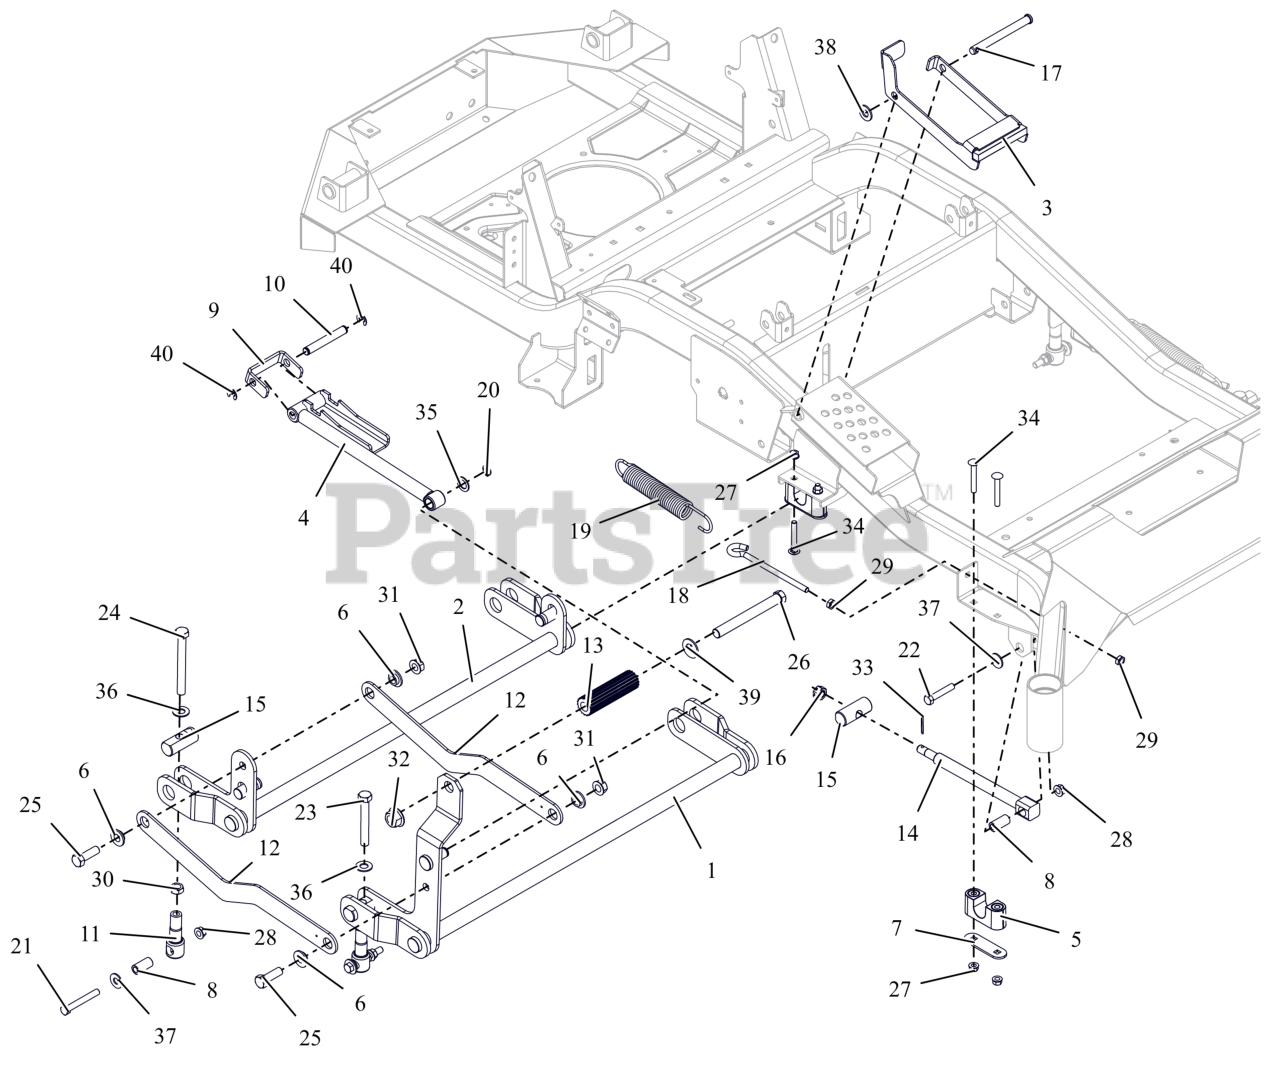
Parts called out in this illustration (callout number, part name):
1	WLDMT, FRONT DECK LIFT PIVOT
2	WLDMT, REAR DECK LIFT PIVOT
3	BRKT, HOC TRANSFER LOCK
4	WLDMT, HOC ARM
5	ASM-BUSHING, DECK LIFT
6	BSHG-FLG .515X.750X.395X1.120
7	PLATE, BEARING SUPPORT
8	SPACER, DECK LEVELING
9	BRKT, HOC LINE
10	ROD, HOC PIVOT
11	LINK, DECK LIFT FORMED
12	LINK, DECK LIFT
13	ROD, FOOT PEDAL (BLACK)
14	DRAG,LINK-HD
15	PIN, DECK LIFT
16	NUT-SL .50-13
17	PIN-SLIC .50X4.97X4.55 -ZCC
18	BOLT,.38-16 X 5.25-.62 DIA EYE
19	SG-TENS .162X1.25X8.25 WLD 25
20	RG-RTNG-EXT .625X.050
21	BLT, HEX .38-16X2.75 G8 ZCC
22	BLT,HEX .38-16X2.00 G5 ZCC
23	BLT, HEX .50-13X3.50F G5 ZCC
24	BLT, HEX .50-13X4.50F G8 ZCC
25	BLT,HEX .50-13X1.50 G5 ZCC
26	BLT, HEX .62-11X5.50 G5 FBP
27	NUT,LK-CTR-FLG .31-18 GF ZCC
28	NUT-LK-TOP-FLG .38-16 ZC120
29	NUT-JAM .375-16 G2 ZCC
30	NUT-JAM .500-13 G2 ZCC
31	NUT-LK-TOP-FLG .500-13 GF ZCC
32	NUT,FLG-TOP LK .625-11 FBP
33	PIN,CTR.12X1.25EXTPRSQCT ZC120
34	BLT, RHSSN.31-18X2.25 G5 ZCC
35	WSHR, FLT .630X1.005X.062 ZCC
36	WSHR, FLT .557X1.040X.102 ZCC
37	WSHR,FLT .438X1.00X.083 ZCC
38	WSHR,FLT .531X1.062X.095 ZCC
39	WSHRFLT 5/8SAE CARBHARD FBP
40	RG-RTNG-EXT .500X.042 (E)
